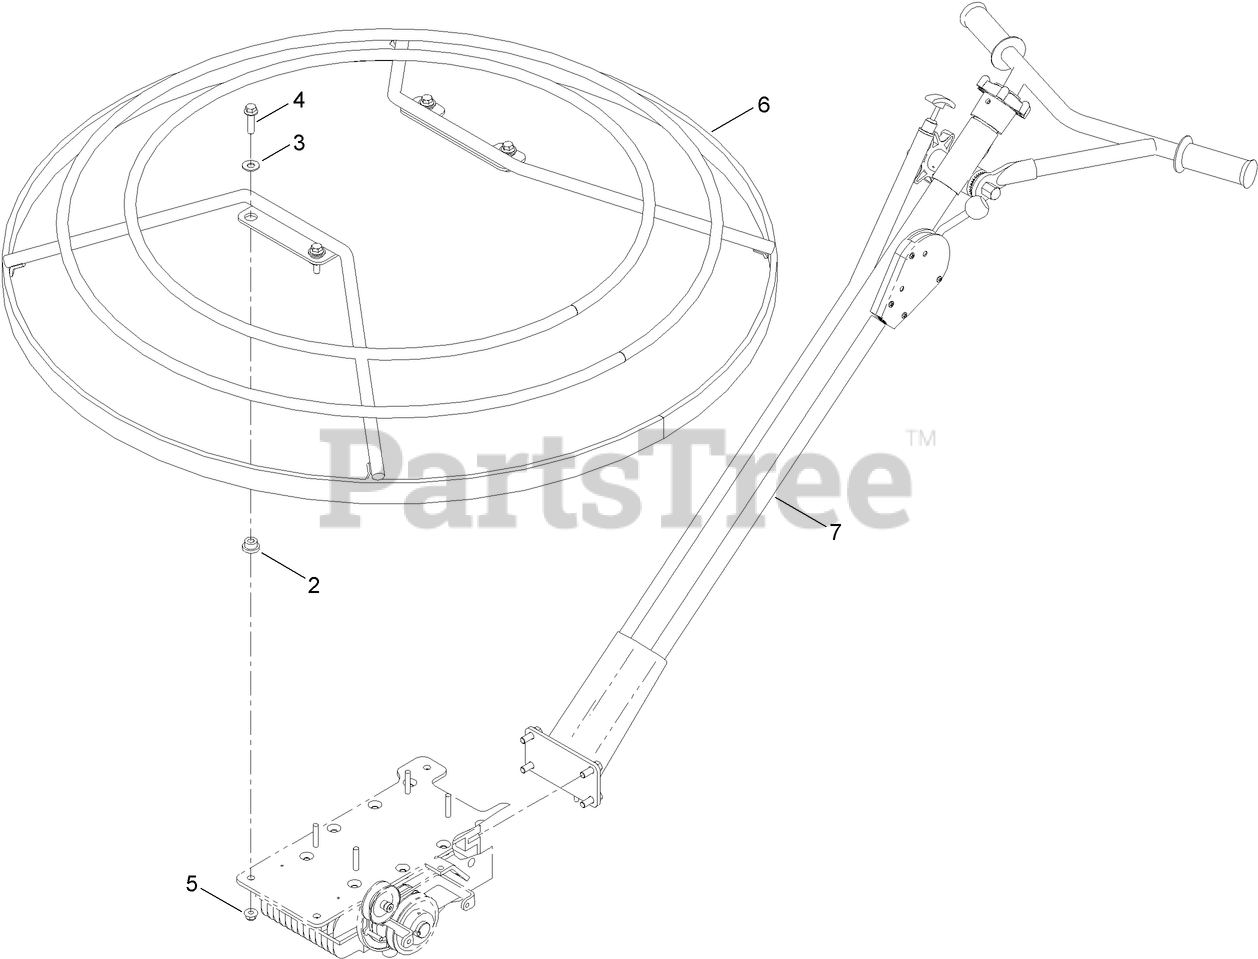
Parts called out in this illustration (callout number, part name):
2	MOUNT-SHOCK
3	WASHER-FLAT
4	SCREW-HHF
5	NUT-HF, NI
6	GUARD-STATIONARY
7	HANDLE-STANDARD
